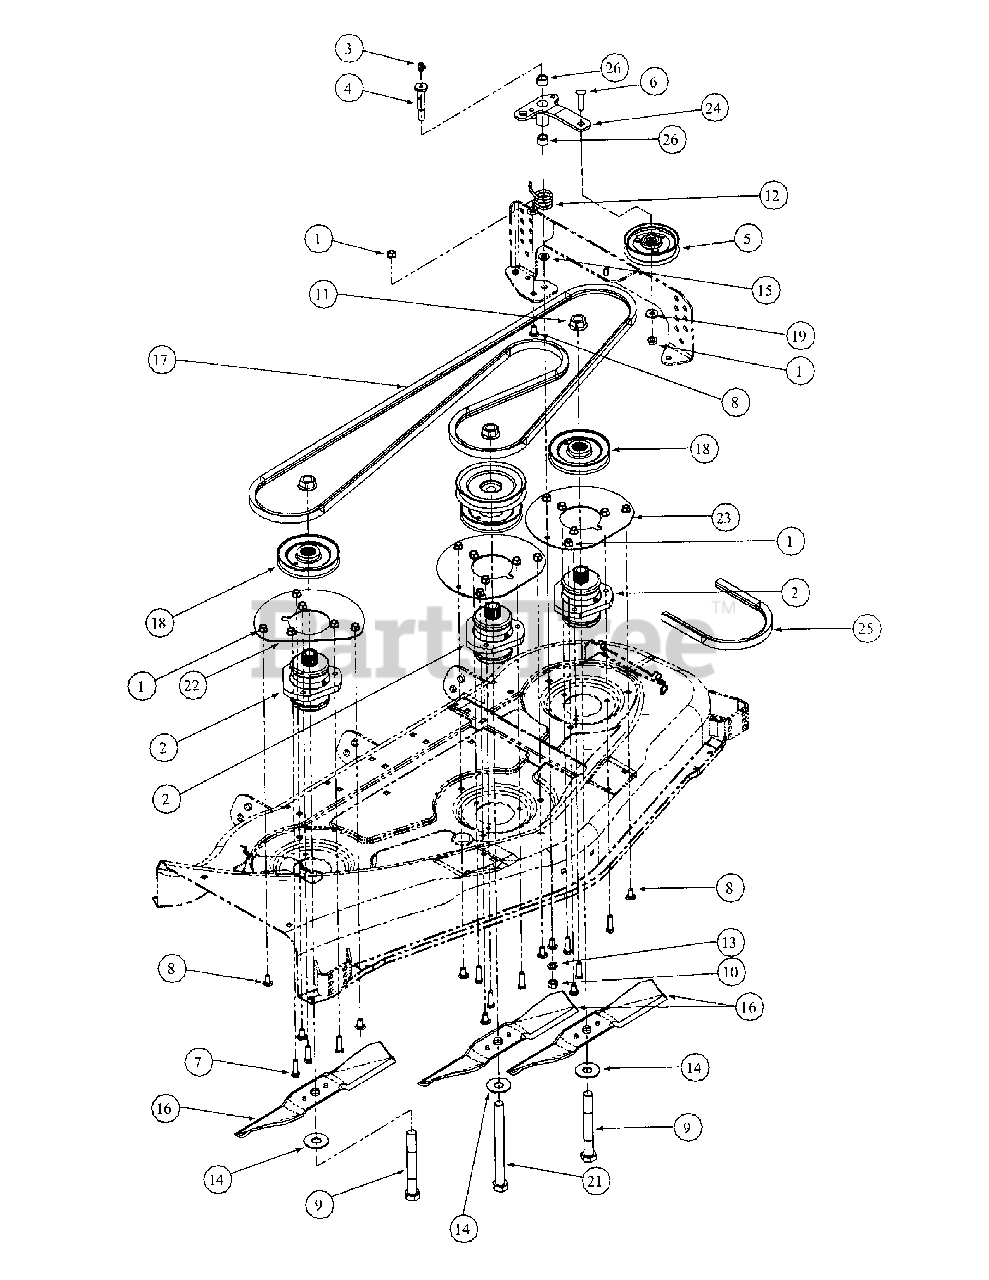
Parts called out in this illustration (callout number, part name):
1	Hex Nut, 3/8-16 Flange Lock
2	Spindle Assembly w/Cups
3	Fit, 90 Tapper Grease 1/4-28
4	Shoulder Screw, 7/16-14
5	Idler Pulley Assembly, 4.00"
6	Screw, 3/8-16, 1.75 Hex Carrier
7	HHCS, 3/8-16, 1.25
8	Carrige Bolt, 3/8-16 x .75 LG.
9	HHCS, 3/4-16, 6.00
10	Nut, Hex, 7/16-14
11	Nut, Hex Flange, 3/4-16
12	Spring Idler Torsion
13	Lock Washer, 7/16
14	Flange Washer, .781, ID: 2.00 OD: .105
15	Flange Washer, .469, ID: .875 OD: .105
16	Mower Blade 16.5 LG. High Lift
17	V Belt, A Sect x 107.3 LG
18	Pulley-V 4.65 P.O.
19	Washer, Flange, .406 ID: 1.0 OD-.105
20	Double Pulley
21	HHCS: 3/4-16, 8.00
22	Cover Plate, Right Hand
23	Cover Plate
24	Idler Arm Assembly, W/Briggs
25	V Belt, B Sect x 63.04 EL
26	Bearing Sleeve
